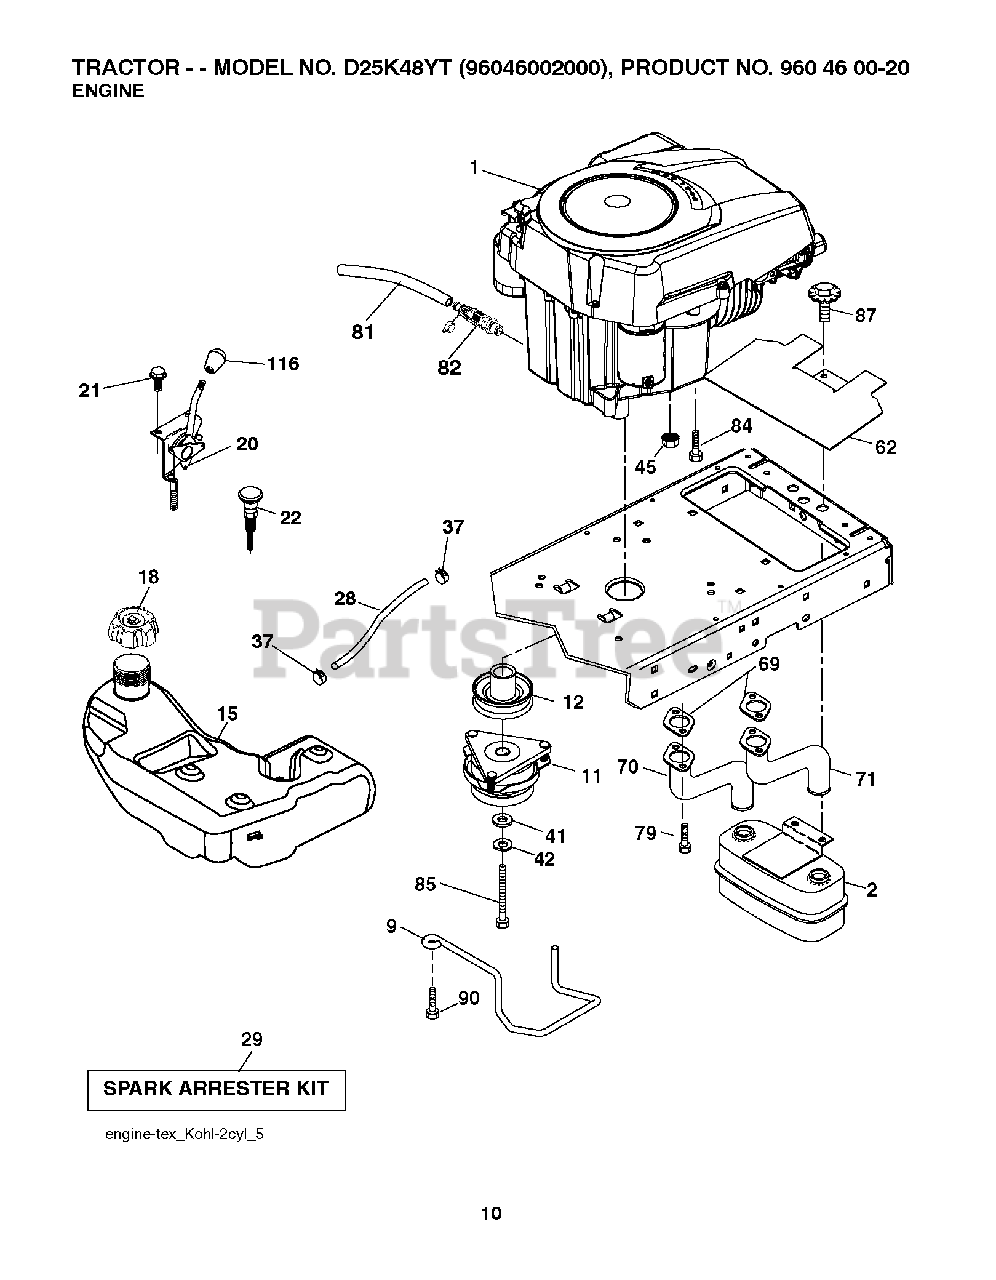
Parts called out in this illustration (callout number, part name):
2	MUFFLER.TWIN.CYL.LOW.TONE
9	KEEPER.BELT.ENGINE.4.2
11	CLUTCH.ELECTRIC.LT.48"*
12	PULLEY.ENGINE.TUFFTORQ
15	TANK.FUEL.SIDE-FILL.3.NON-EPA
18	CAP.ASM.FUEL.TANK.3"BLACK
20	CONTROL.THROTTLE.PRO.
21	SCREW.#10 X 0.750.BOS (2 2)
22	CONTROL CHOKE
28	LINE.FUEL.64"REAR.EMIS
29	KIT.SPARK ARRESTOR(392390 B&S)
37	HOSE CLAMP
42	LOCKWASHER
45	NUT
62	SHIELD.HEAT.MUFFLER
70	RP.PIPE-EXHAUST LH
71	RP.PIPE-EXHAUST RH
79	SCREW.SOCKET HD.5/16-1
81	TUBE, DRAIN OIL ASM.
82	VALUE.OIL.DRAIN
84	SCREW 3/8-16X1
85	BOLT HEX 7/16-20X4-1/4"
87	BOLT.5/16-18UNCX1.W/SEMS.BLK
90	SCREW 3/8-16X1
116	RP KNOB SOFT TOUCH
